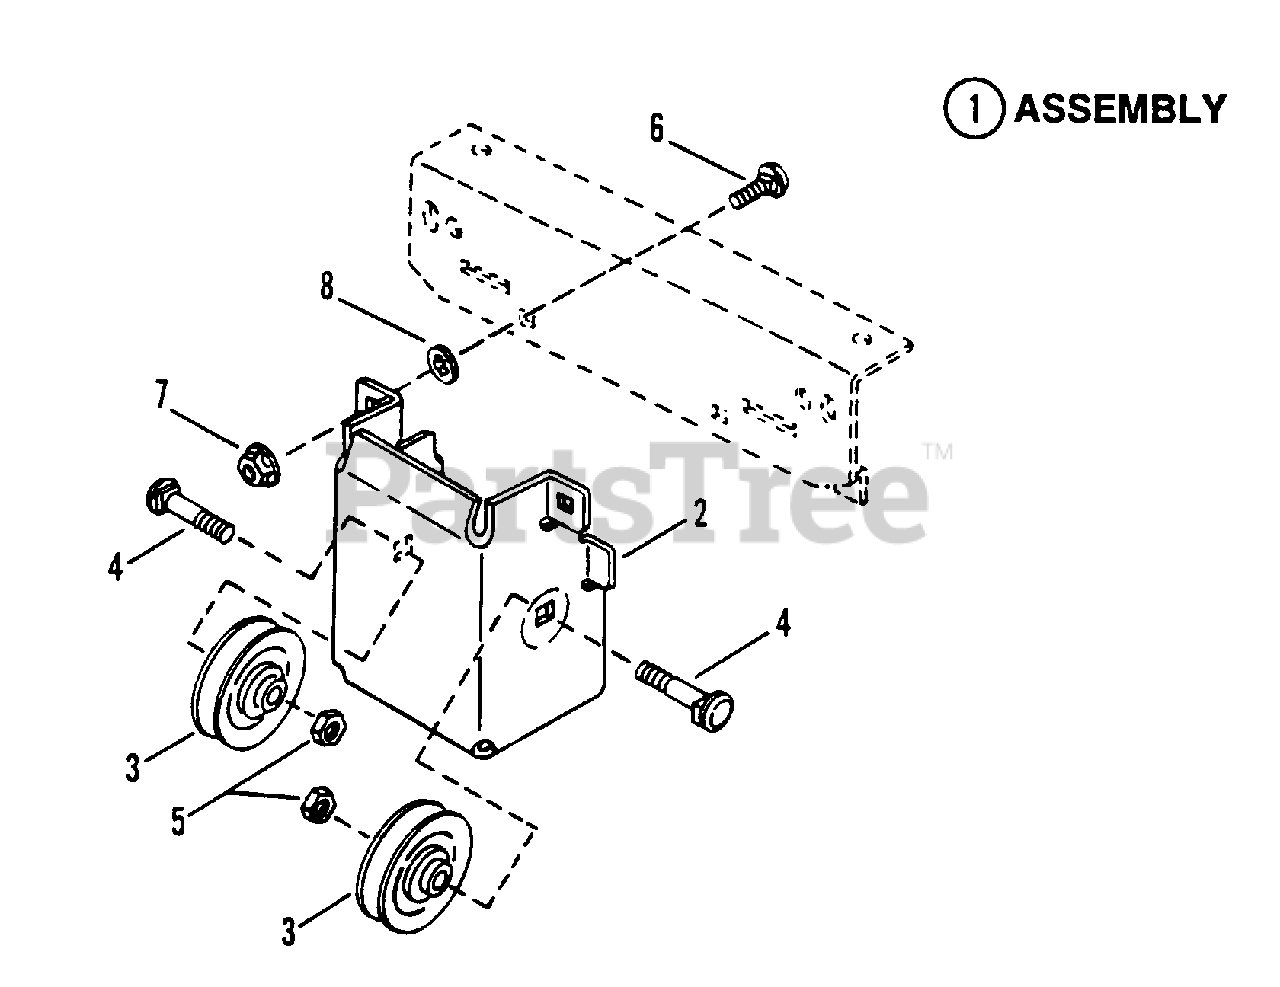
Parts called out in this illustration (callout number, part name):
1	ASSEMBLY, Mule Drive
2	BRACKET, Mule Drive
3	PULLEY, Belt Idler
4	BOLT, 3/8-16 x 1-1/2" Short Neck Carriage, Grade 2
5	NUT, 3/8-16 Hex
6	BOLT, 3/8-16 x 3/4" Carriage, Grade 2
7	NUT, 3/8-16 Hex Flange
8	RETAINER, 3/8 Bolt
